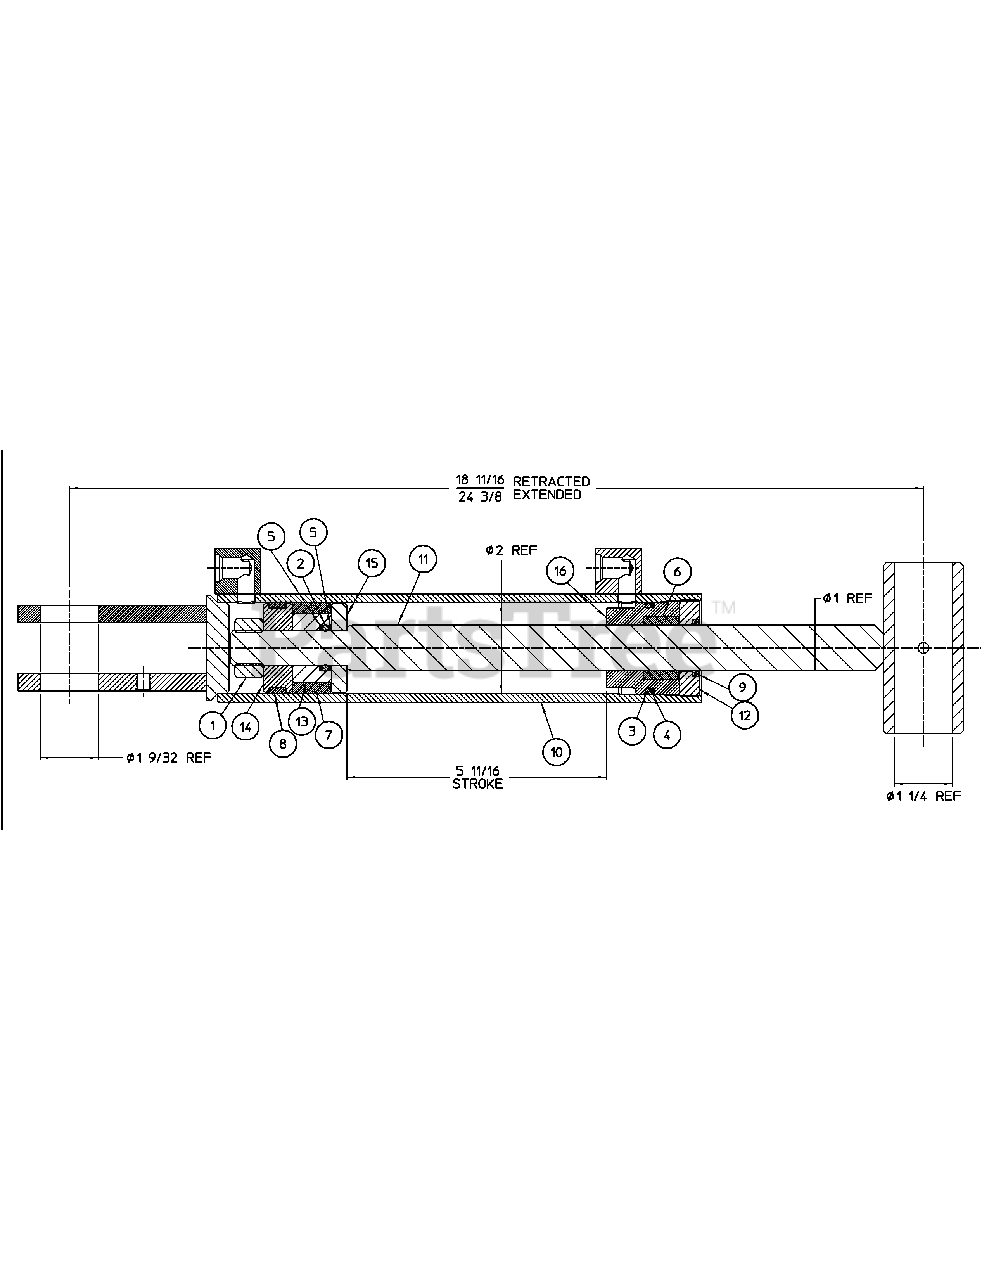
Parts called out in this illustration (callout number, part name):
1	Nut, Hex 3/4-16 Gr 5 Lock
2	O-Ring, 1" OD x 3/4 ID
3	O-Ring
4	Back-Up Ring
5	Back-Up Ring
6	V-Ring Packing
7	V-Stack
8	Wear Ring
9	Rod Wiper
10	Cylinder Tube Weldment
11	Piston Rod Weldment
13	Piston Spacer
15	Piston Washer
